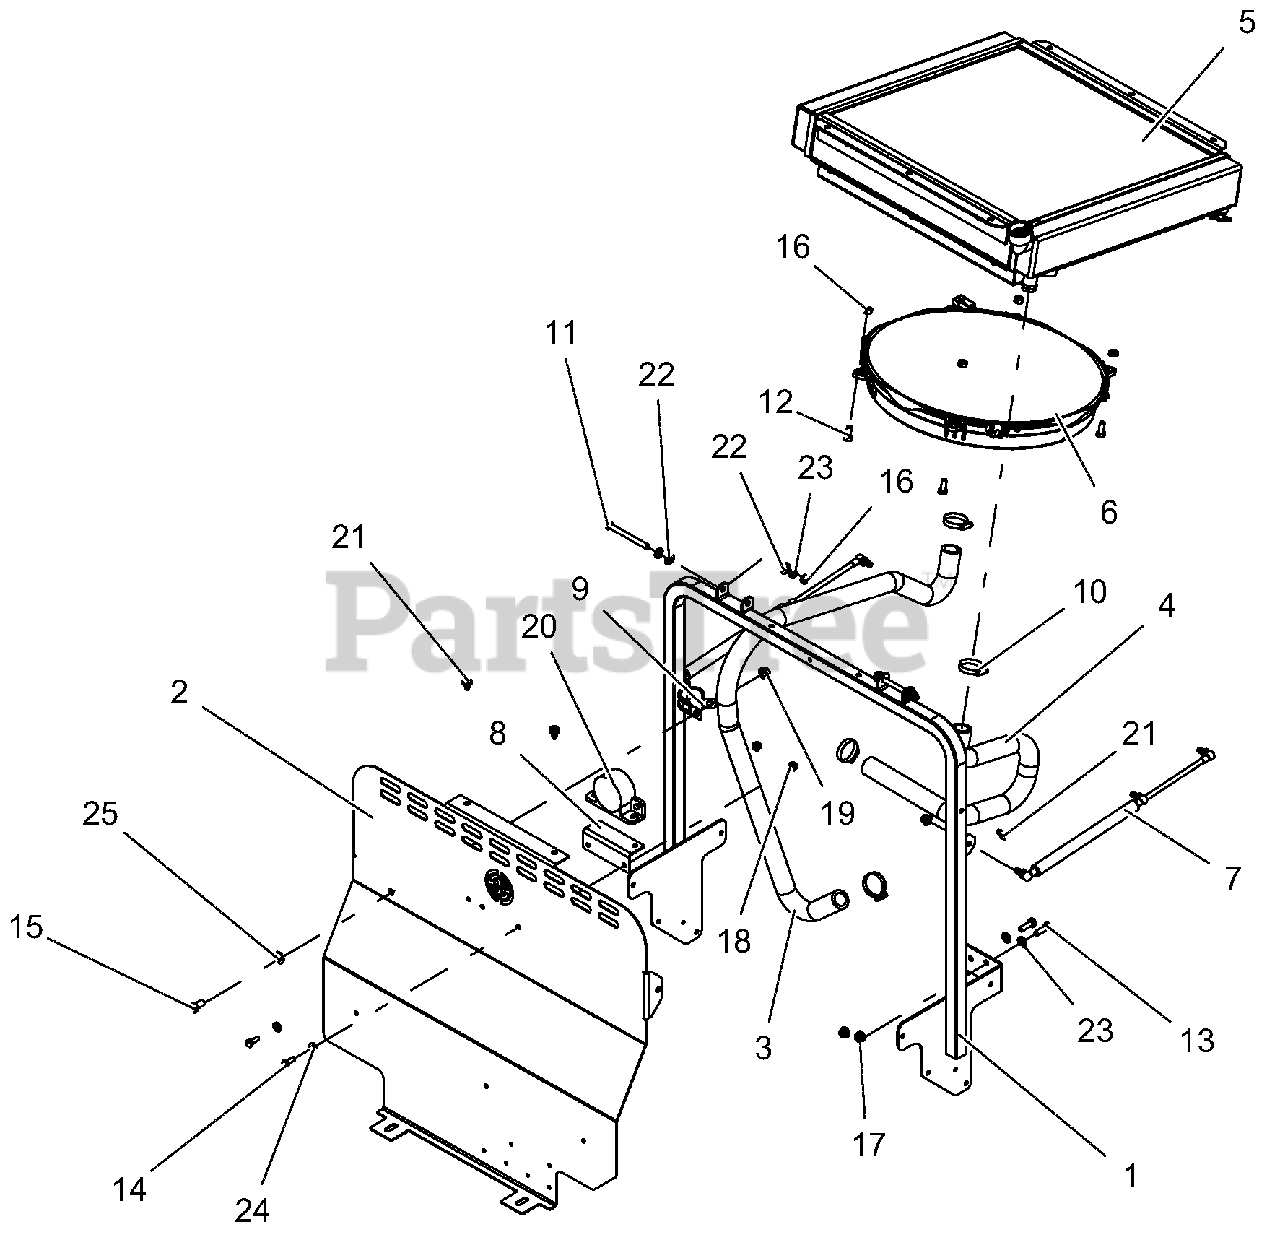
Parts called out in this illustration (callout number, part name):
1	WLDMT, RADIATOR / EXP. TANK MOUNTK-BLAC
2	GUARD, OPERATOR PT400 DIESEL
3	HOSE, FORMED RADIATOR OUTLET
4	HOSE, FORMED RADIATOR INLET
5	RADIATOR, DIESEL PT-400
6	FAN, COOLING 16"
7	STRT, RADIATOR FRAME-YELLOW
8	BRKT, SIGNAL MOUNT
9	CLAMP, CUSHIONED STEEL5, 1.2
10	CLAMP, HOSE 1.50 X .81 X 1.42
11	BLT-HEX .31-18X3.50 GR5 YWZC
12	BLT-HEX .31-18X.75 GR5 YWZC
13	BLT-HEX .31-18X1.00 GR5 YWZC
14	BLT-HEX .25-20X.75 GR5 YWZC
15	BLT-HEX .38-16X.75 GR5 YWZC
16	@NUT-LK-CTR .31-18 YWZC
17	NUT-LK-NYL-FLG .31-18 YWZC
18	NUT-LK-NYL-FLG .25-20 YWZC
19	@NUT-SPNLK-FLG .375-16 YWZC
20	ALARM, BACKUP
21	SCR-TAP .31-18X.50 HWH TR YWZ
22	WSHR-FL-NYL .375X.75X.060
23	@WSHR-FL-STL.344X.688X.065YWZC
24	@WSHR-FL-STL.281X.62X.065 YWZC
25	@WSHR-FL-STL.406X.812X.065 YWZ
